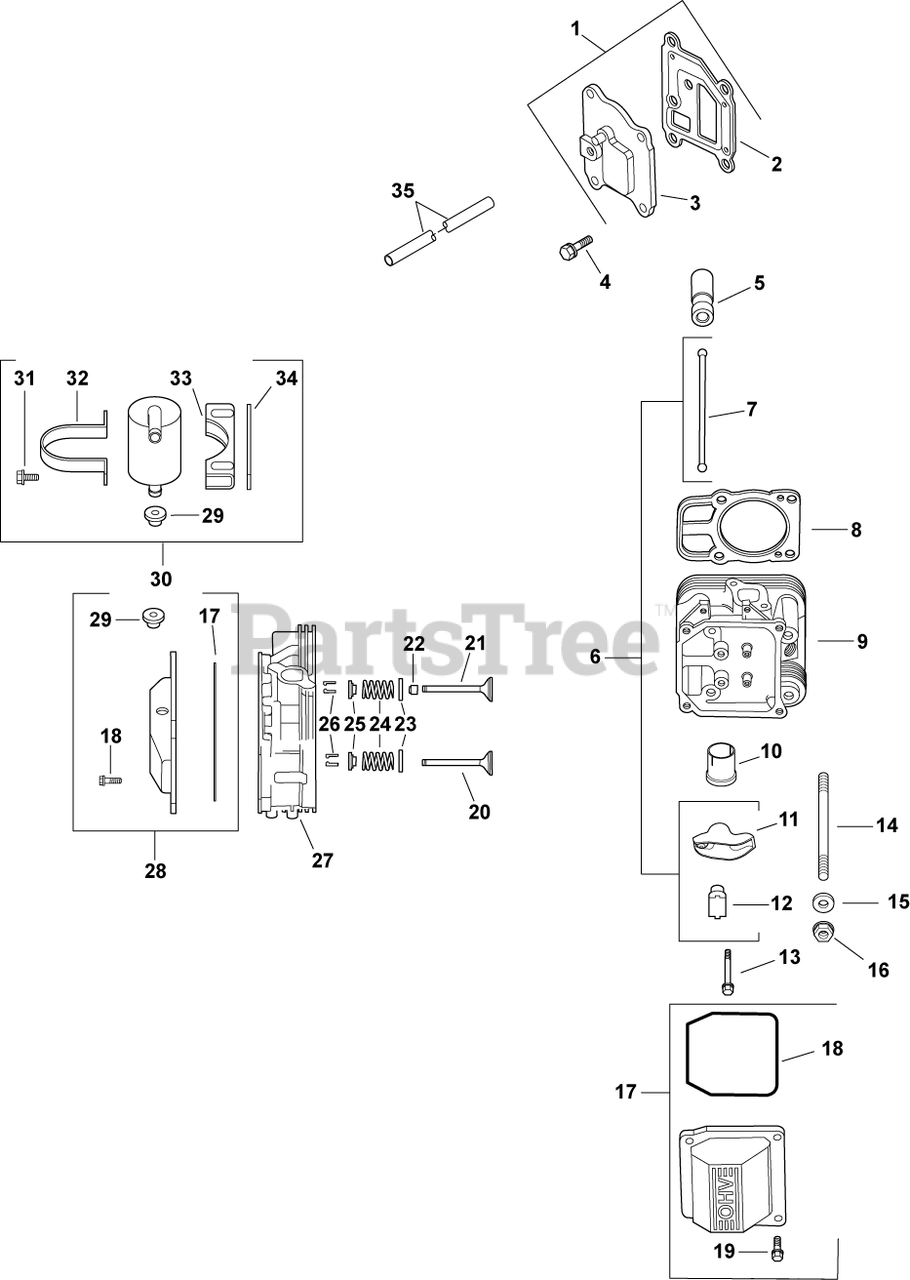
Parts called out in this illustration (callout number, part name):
1	KIT, BREATHER COVER W/GASKET
2	GASKET, BREATHER-USE 24 041 67-S
3	COVER, BREATHER -USE 24 096 125-S
4	SCREW,FLG THD FRM M6X1.0X20-(#25086396S)
5	LIFTER, HYDRAULIC VALVE-USE 25 351 10-S
6	KIT, VALVE TRAIN
7	ROD, PUSH
8	CYL HEAD GASKET KIT-USE 24 841 04-S
9	HEAD, ASSEM CYLINDER #2 -USE 24 318 116-
10	LINER, EXHAUST PORT-USE 24 605 07-S
11	ARM, ROCKER
12	PIVOT, ROCKER ARM
13	SCREW, FLG M6X1.0X34
14	STUD, M8X1.25
15	WASHER, FLAT 8.6 MM
16	NUT, FLG M8X1.25
17	KIT, VALVE COVER-PLAIN
18	O-RING (YELLOW) -USE 24 153 30-S
19	SCREW, FLG M6X1.0X30
20	VALVE, EXHAUST (STD) - USE 32 016 01-S
21	VALVE, INTAKE (STD)
22	SEAL, VALVE STEM - (#2503214S)
23	RETAINER, SPRING
24	SPRING, VALVE
25	RETAINER, VALVE SPRING - USE 25 173 28-S
26	KIT, RETAINER
27	HEAD, ASSEM CYLINDER #1 -USE 24 318 108-
28	KIT, VALVE COVER
29	GROMMET, RUBBER
30	KIT, BREATHR SEPARATR-(#24755241S)
31	SCREW,FLG THD FRM M5X0.8X16-(#25086398S)
32	STRAP, BREATHER - USE 24 755 241-S
33	BRACKET, BREATHER SEPARATOR
34	SPACER
35	HOSE, BREATHER-USE 24 326 63-S
2401602-S	VALVE, EXHAUST (.25)
2401702-S	VALVE, INTAKE (.25)
